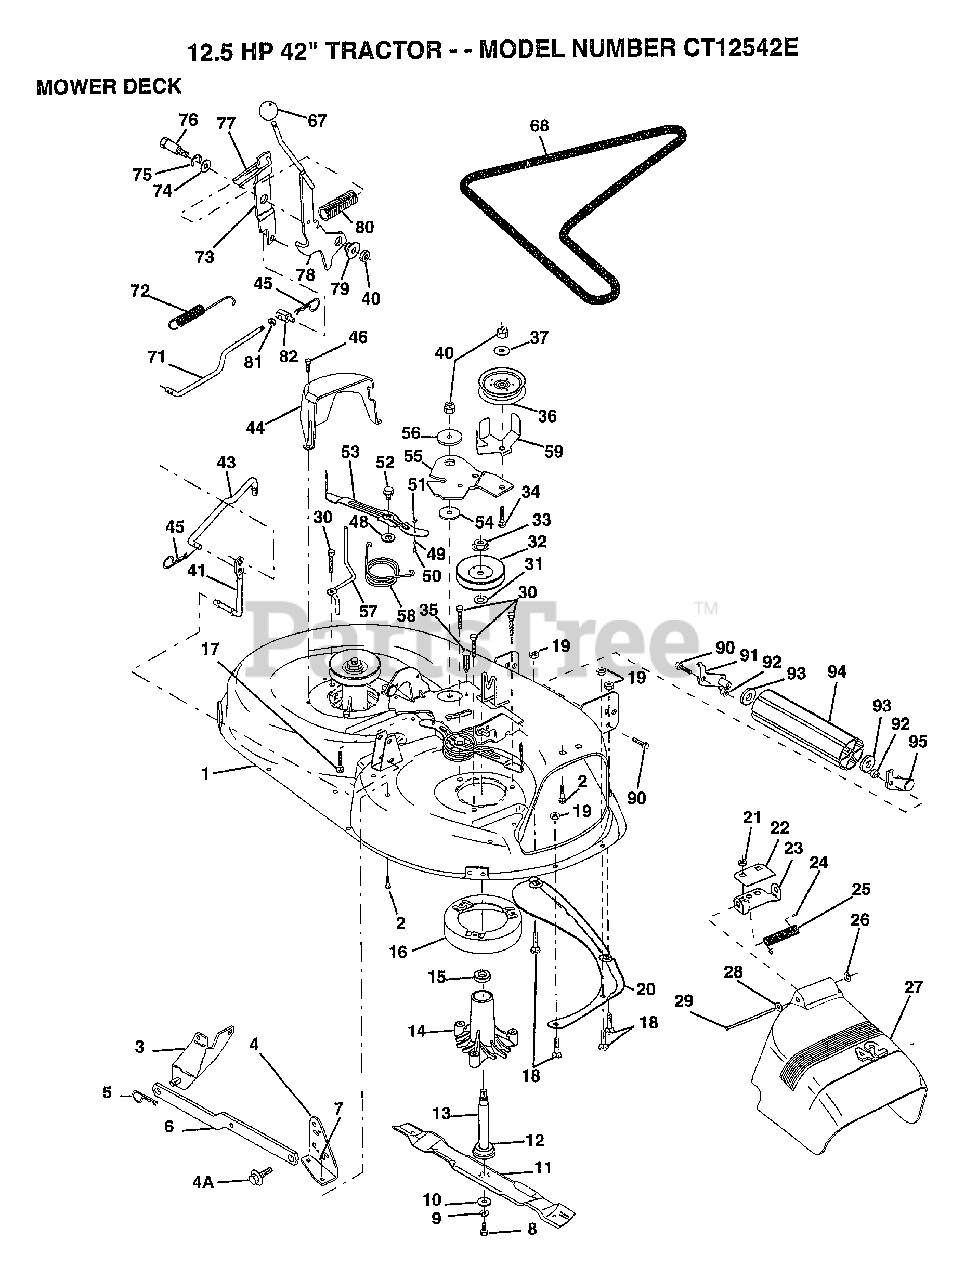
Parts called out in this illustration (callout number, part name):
2	BOLT
3	BRKT ASM SWAY BAR
4	BRKT DECK SW BAR
4A	BOLT SHD 5/16-18
7	NUT
8	BLADE BOLT
10	WASHER.HARD.BLADE
11	"BLADE.42"" MULCHER"
12	BEARING.BALL
14	HSG ASM MANDREL
15	BEARING
16	STRIPPER RND MWR
17	BOLT RDHD 3/8-16
18	BOLT
19	NUT
21	NUT
22	STIFFENER BRKT
23	DEFLECTOR BRKT
24	CAP-SLEEVE LT
25	SPRING TORSION
26	NUT PUSH M
27	DEFLECTOR.SHIELD
28	WASHER
29	HINGE ROD
31	WASHER
34	BOLT
35	XMAS TREE FASTNER
36	FLAT IDLER PULLEY
37	WASHER
40	NUT
41	PIVOT ROD
43	ROD CLUTCH W/NIBS
44	GUARD MAND LH BLK
45	RETAINER M
46	SCREW.1/4-20X5/8
48	HARD SMALL WASHER
50	SHOULDER BOLT
51	LOCKNUT
52	BOLT.SHLD.5/16-18
53	BRAKE PAD ARM ASM
54	HARDENED WASHER
56	SPACER RETAINER
57	KEEPER BELT LH 42
58	SPRING TORSN BRAK
59	GUARD IDLER TUV
68	BELT-V MWR 82.625
71	ROD CLUTCH 38/42
72	RETURN SPRING
73	CLUTCH ARM SECOND
74	WASHER
75	RING
76	SHOULDER BOLT
77	SPRING KEEPER
79	BUSHING
81	NUT
82	TRUNION ADJ
90	BOLT
92	NUT
93	WASHER
